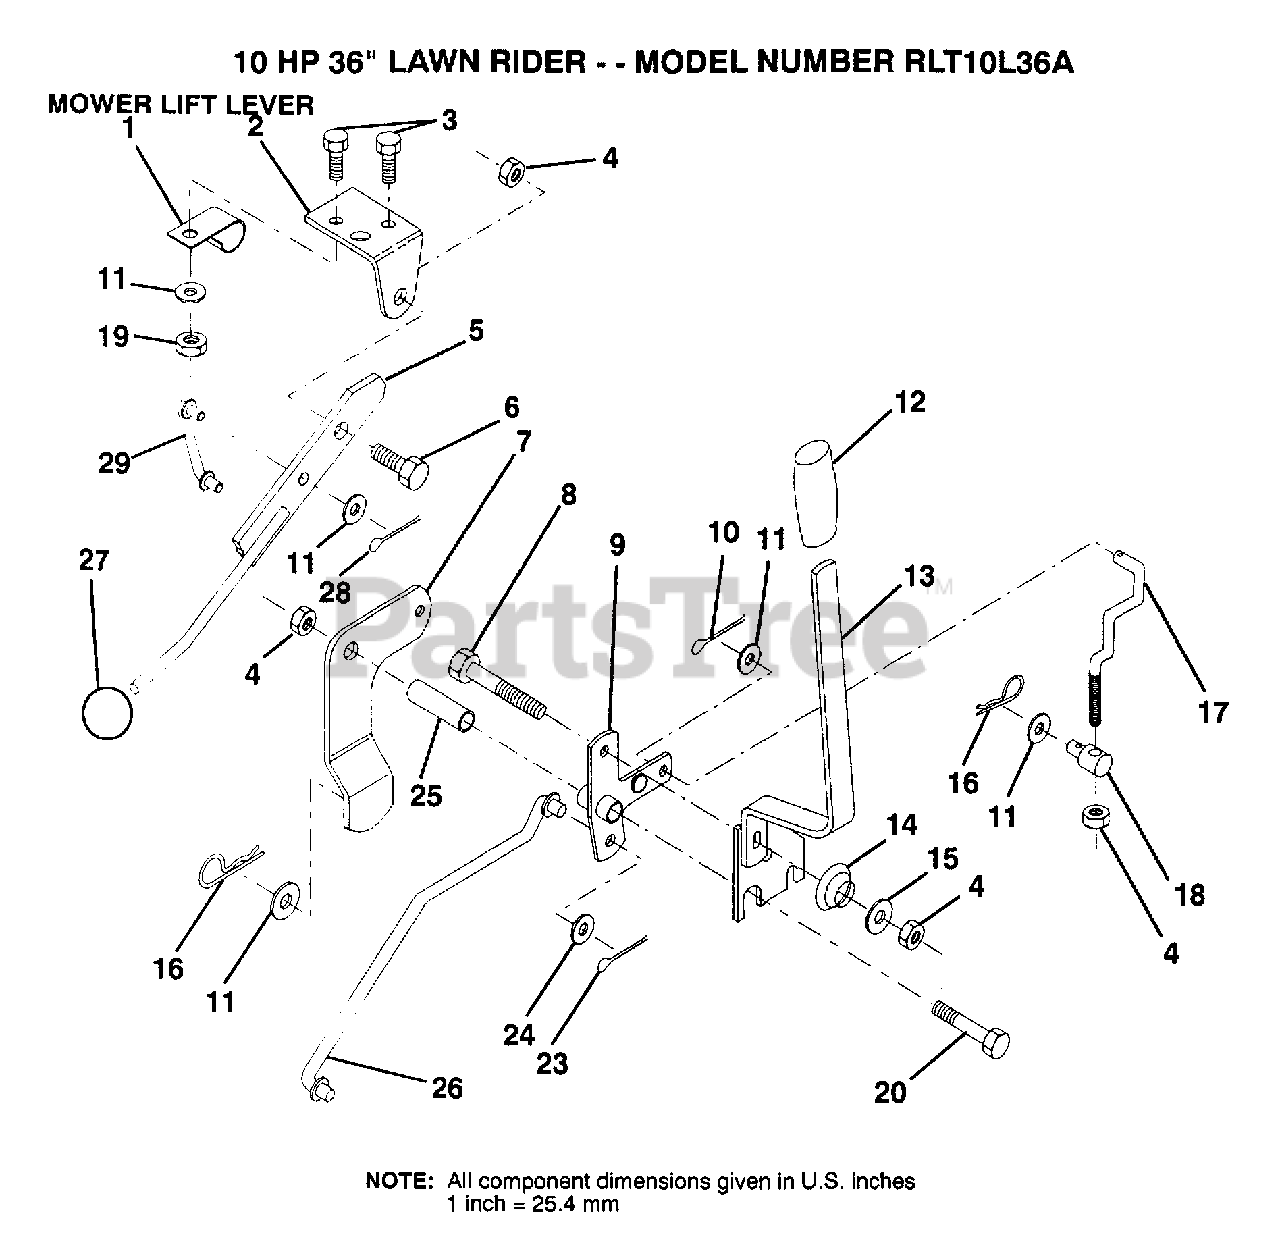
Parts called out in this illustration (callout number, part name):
1	"CLIP,INSULATOR"
2	BRKT CLUTCH
3	BOLT
5	CLUTCH LEVER AS
6	"BOLT, SHOULDER LT"
8	BOLT
9	"BELLCRANK,LIFT"
10	COTTER PIN
11	WASHER
13	"HDLE,LIFT T"
14	SPRING COMPRESSIO
15	WASHER T
16	SPRING.RETAINER
17	"LINK,LIFT FRT"
18	TRUNION
20	BOLT
23	PIN COTTER 1/8
25	TUBE SPACER
26	"ROD,MOWER LIFT "
27	KNOB T(3/8 HOLE)
29	CLUTCH LINK
